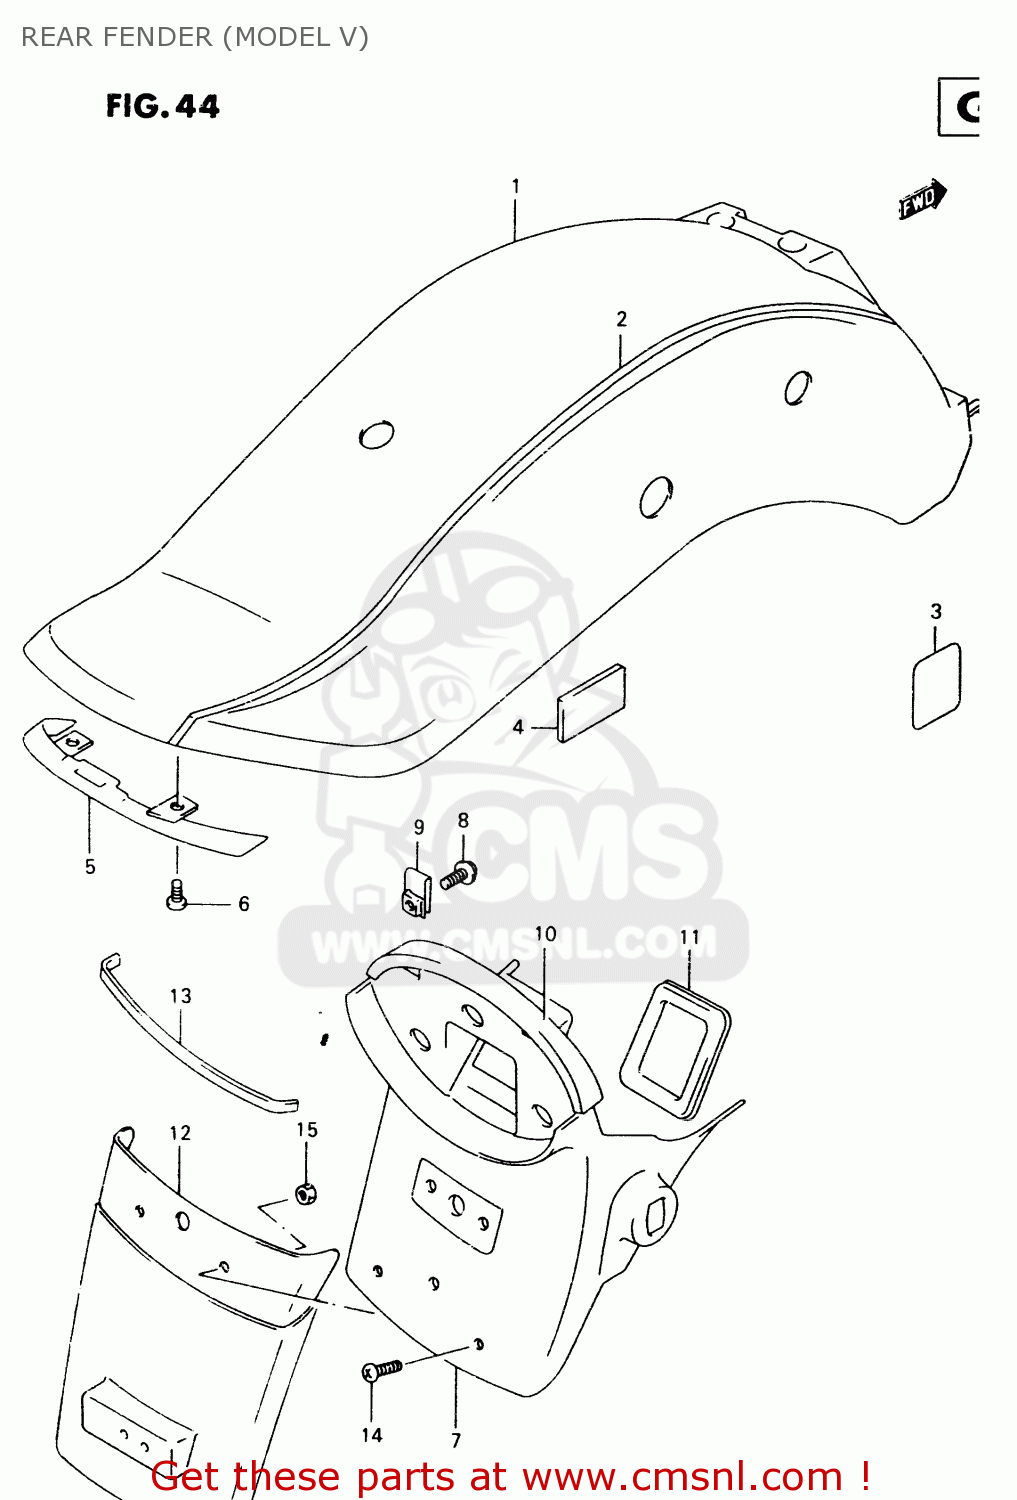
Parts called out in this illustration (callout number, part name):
1	FENDER,RR
2	TAPE SET, REAR FENDER
3	PAD
4	CUSHION
5	COVER,RR FENDER RR
6	SCREW
7	EXTENSION,RR FENDER
8	SCREW
9	PLATE,FRAME COVER
10	CUSHION,RR FENDER EXTENSION
11	CAP,RR FENDER EXTENSION
12	MUDGUARD,RR FENDER
13	CUSHION,RR FENDER EXTENSION
14	SCREW
15	NUT
